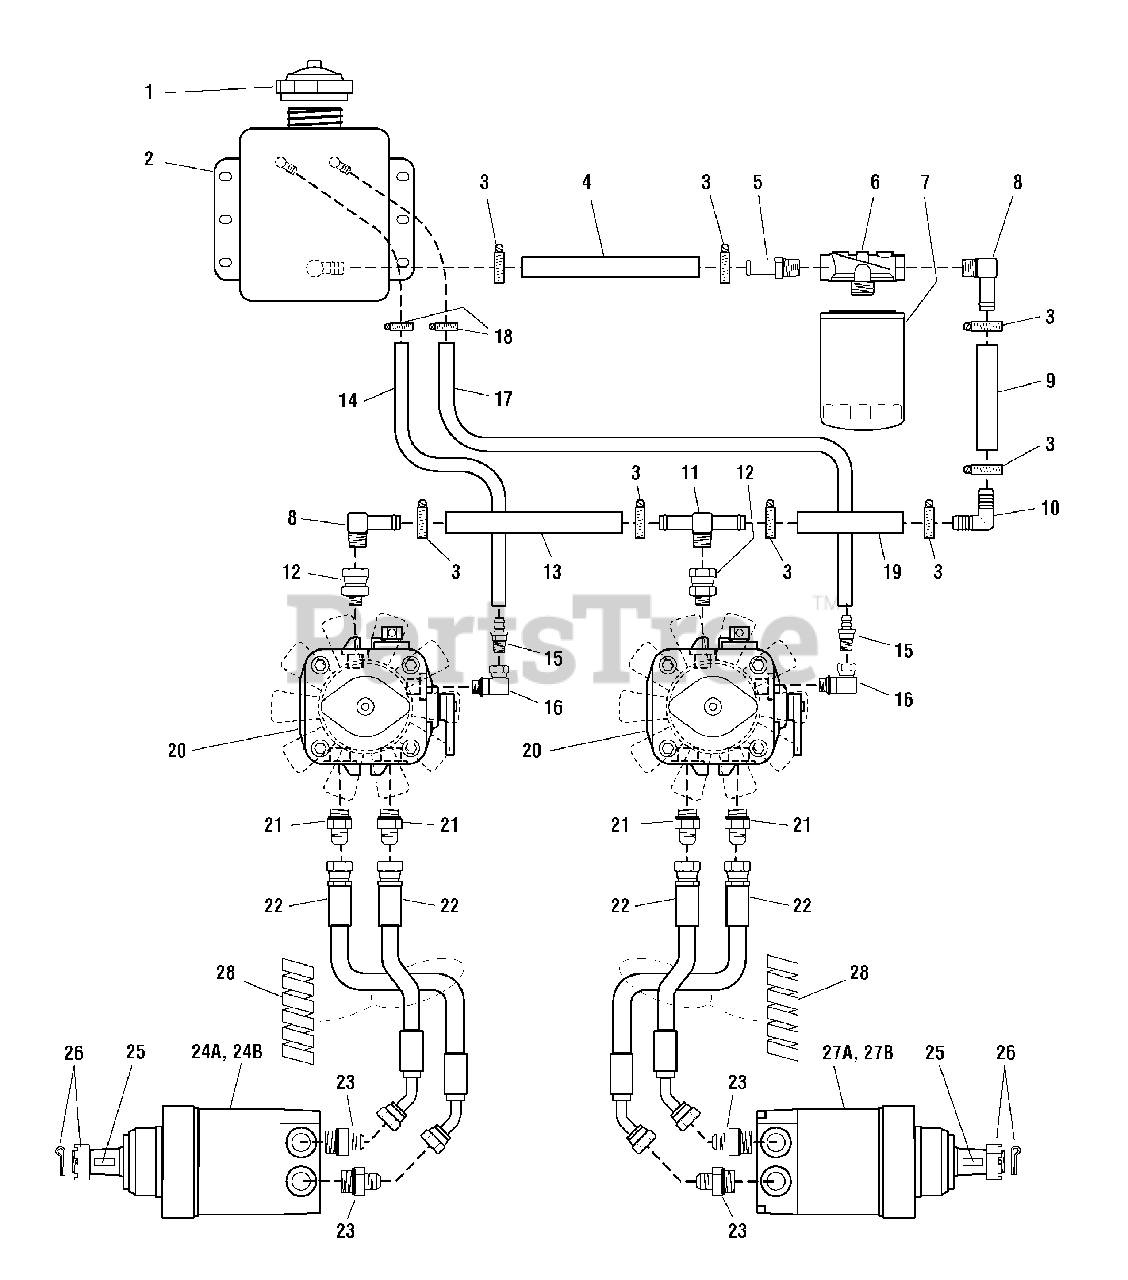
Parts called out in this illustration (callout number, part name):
2	RESERVOIR
3	HOSE CLAMP, #10
4	HOSE, Hydraulic, 11"
5	FITTING, 1/2" NPT, Straight
6	FILTER HEAD
8	FITTING, 1/2" NPT, 90 Deg.
9	HOSE, Hydraulic, 3-1/2"
10	FITTING, 5/8", 90 Deg.
11	FITTING, 1/2" NPT, Tee
12	FITTING, Hydraulic, Straight Swivel
13	HOSE, Hydraulic, 12"
14	HOSE, Hydraulic, 16"
15	FITTING, 1/4" NPT, Straight
16	FITTING, Hydraulic, O-Ring, 90 Deg. Swivel
17	HOSE, Hydraulic, 24"
18	HOSE CLAMP, #6
19	HOSE, Hydraulic, 3"
20	HYDRAULIC PUMP w/ FAN
21	FITTING, Hydraulic, O-Ring Adapter
22	HYDRAULIC HOSE ASSEMBLY
23	FITTING, Hydraulic, O-Ring Adapter
24A	HYDRAULIC WHEEL MOTOR-LEFT, 18 CI, Complete (includes Ref 25 & 26)(S/N: 877 & below)
24B	HYDRAULIC WHEEL MOTOR-LEFT, 15 CI, Complete (includes Ref 25 & 26)(S/N: 878 & above)
26	NUT & COTTER PIN
27A	HYDRAULIC WHEEL MOTOR-RIGHT, 18 CI, Complete (includes Ref 25 & 26)(S/N: 877 & below)
27B	HYDRAULIC WHEEL MOTOR-RIGHT, 15 CI, Complete (includes Ref 25 & 26)(S/N: 878 & above)
28	PROTECTIVE COIL, 12"
